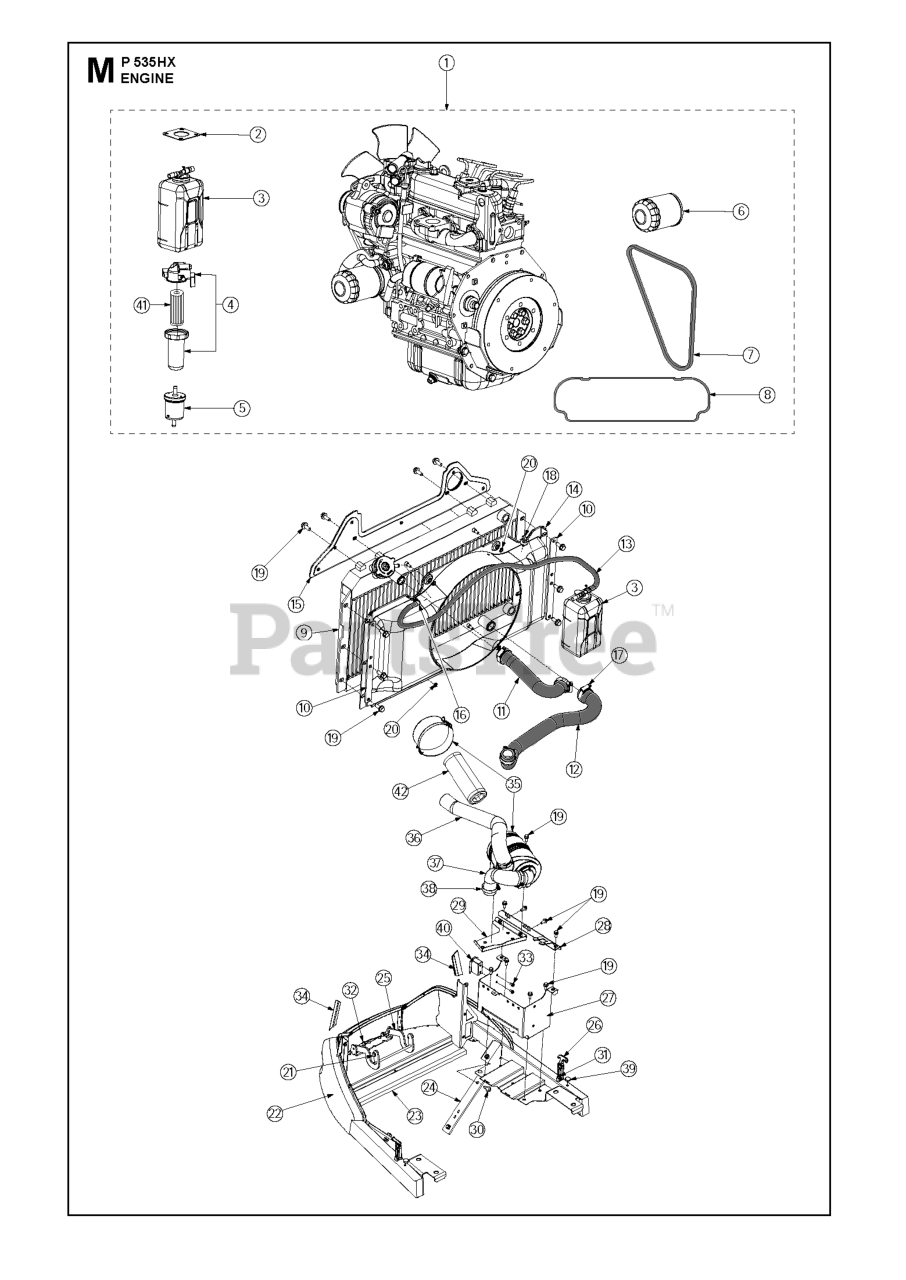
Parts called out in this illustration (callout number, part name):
16	RP HOSE CLAMP FUEL HOSE
31	SCREW IHSCM
33	SCREW EHHFM
